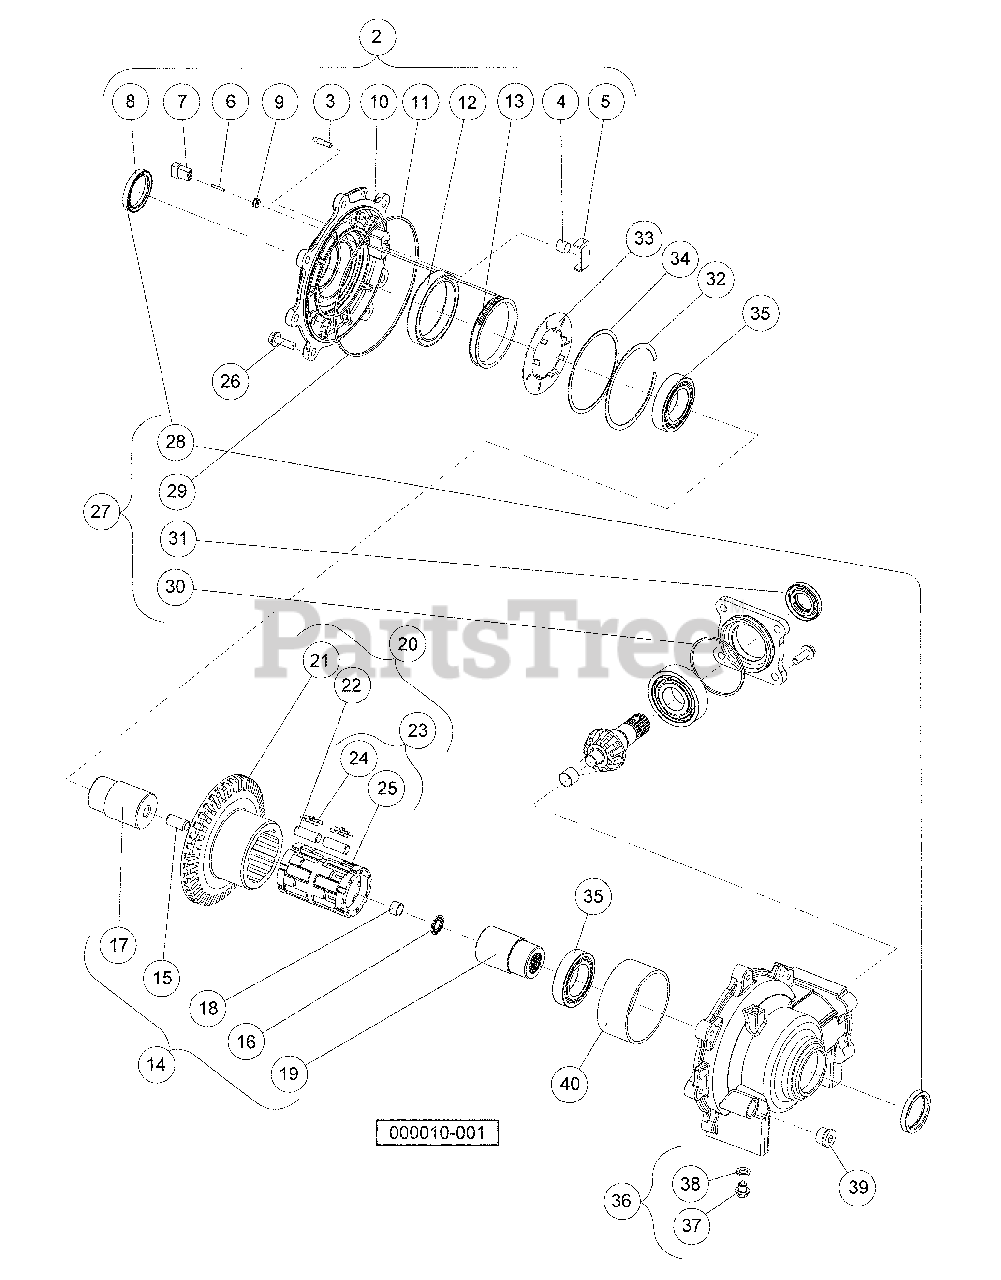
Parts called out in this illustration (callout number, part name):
1	Differential, Front
2	Kit, Assy, Output Cover Plate
3	Set Screw, #10-24 UNC-3A with Patch
4	Thrust Button
5	Thrust Plate
6	Mate-N-Lock Pin
7	Mate-N-Lock Housing
8	Oil Seal
9	Grommet
10	Plate, Output Cover
11	O-Ring
12	Coil, Pocket Insert
13	Coil with Press-Fit Bobbin
14	Kit, Assy, Race Output Hub
15	Pin, Dowel
16	Bearing, Needle
17	Race/Output Hub, Male
18	Bushing, PermiGlide
19	Race/Output Hub, Female
20	Kit, Assy, Clutch
21	Clutch Hsg/Ring Gear, Machined
22	Kit, Roller (contains 14 rollers)
23	Kit, Assy, Roll Cage
24	Kit, H-Clip Spring (contains 14 clips)
25	Roll Cage, Plastic
26	Kit, Bolt (contains 7 bolts)
27	Kit, Minor Repair
28	Oil Seal
29	O-Ring
30	O-Ring
31	Oil Seal, Triple-Lipped
32	Retaining, Ring Internal
33	Plate, Armature
34	Shim, Armature, Plate
35	Bearing, Ball
36	Kit, Assy, Drain Plug
37	Plug, Oil Drain
39	Plug, Oil Fill
